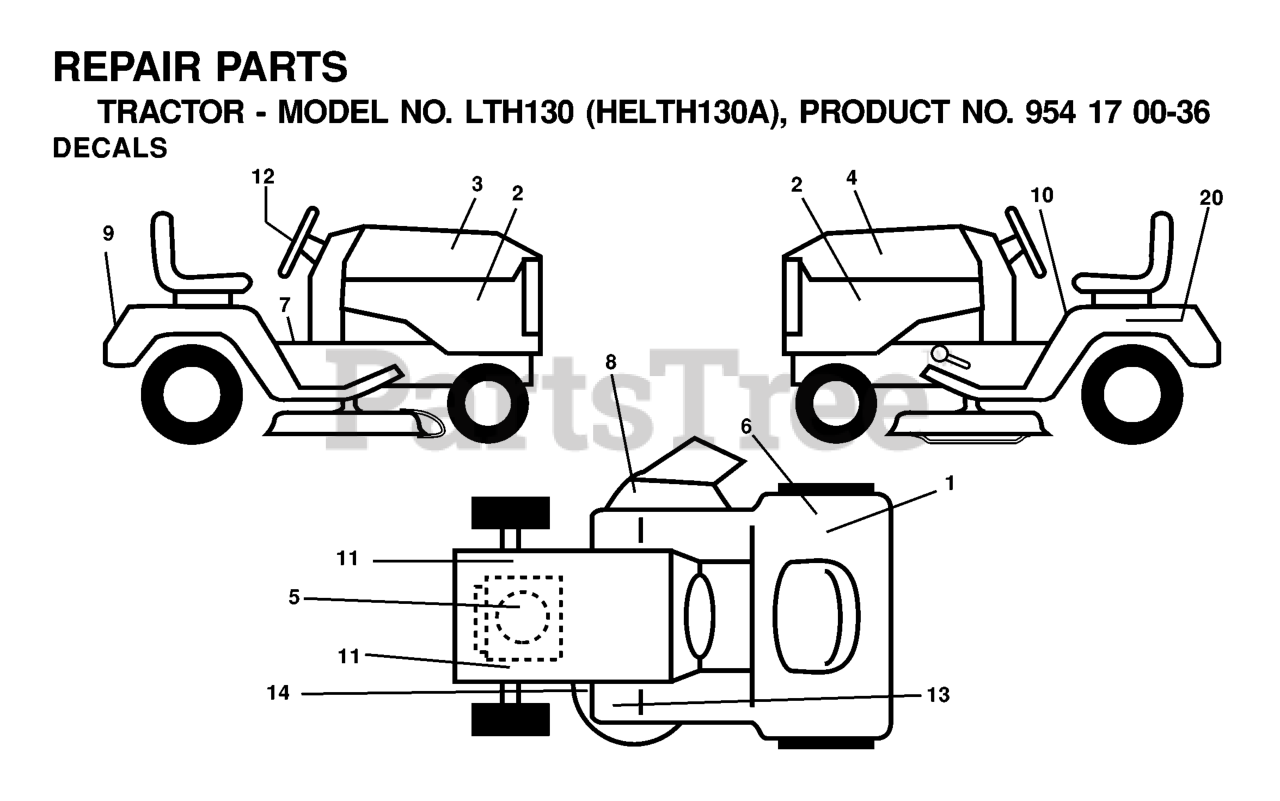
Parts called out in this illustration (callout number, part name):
1	DECAL CERTIFICATION
2	DECAL PNL SIDE
3	DECAL HOOD RH
4	DECAL HOOD LH
5	DECAL HP ENGINE
6	DECAL EUROPE STANDARD CE
7	DECAL PARK BRAKE
8	DECAL MOWER CUT/FINGER
9	DECAL FENDER HUSQ
10	DECAL READ OWNER'S MAN SYMS
12	DECAL.WHEEL.STEERING.HUSQ.PERM
13	DECAL
14	DECAL V-BELT SCHEMATIC
20	DECAL BTRY SYMBOLS
